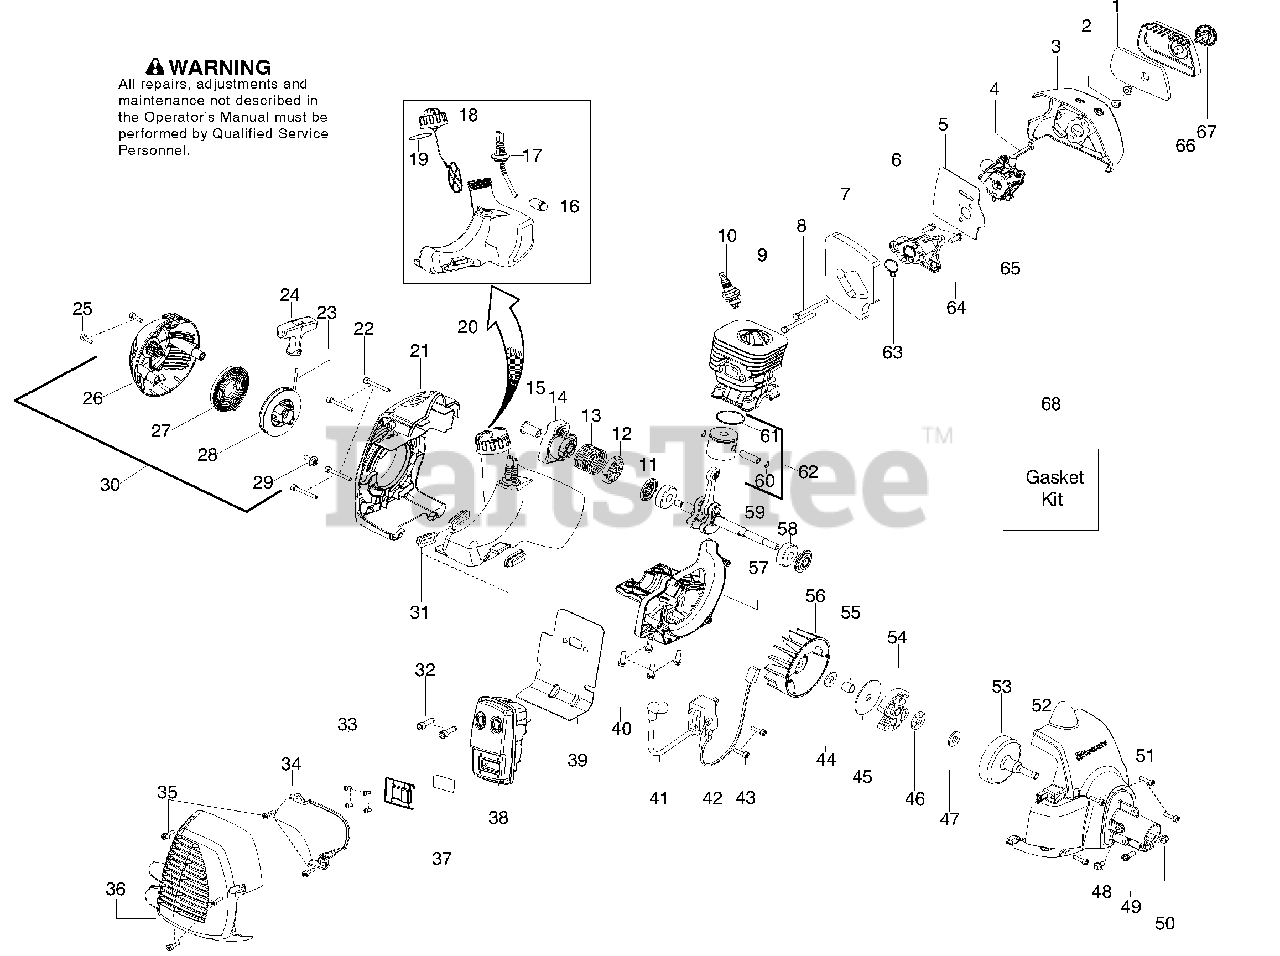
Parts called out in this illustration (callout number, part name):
2	Nut-Carb. Screw
3	Air Box
4	Lever - Choke
5	Kit-Carb. Gasket
6	Adaptor-Carb.
7	Kit-Gasket (foam)
9	Cylinder
10	Plug-Spark (RCJ-8Y)
11	Kit-Crankshaft seal
12	Washer-Starter
13	Spring-Starter Cup
14	Assy-Starter Cup
15	Coupling-Starter
16	Assy-Fuel Filter
17	Kit-Fuel Line
18	Assy-Cap w/ret.
19	Kit-Gasket O-ring - Fuel Cap
20	Assy-Fuel Tank
21	Shroud-Rear
24	Handle-Starter
26	Hsg.-Starter w/eyelet
27	Kit-Starter Spring
28	Kit-Starter Pulley
30	Assy-Starter Hsg.
31	Isolator-Tank
32	Bolt-Muffler
34	Shield-Heat
36	Guard-Muffler
37	Kit-Spark
38	Assy-Muffler
39	Kit-Gasket-Paper Met.
42	Assy-Leadwire
45	Washer-Clutch
46	Bearing - Thrust
47	Washer - Thrust
52	Assy-Fan Housing
53	Assy-Clutch Drum
54	Kit-Clutch Assy.
59	Kit-Crankshaft
60	Retainer-Piston Pin
61	Ring-Piston
62	Kit-Piston
63	Kit-Gasket (adaptor seal)
65	Kit-Carb.
66	Cover-Air Box
68	Kit-Gasket
